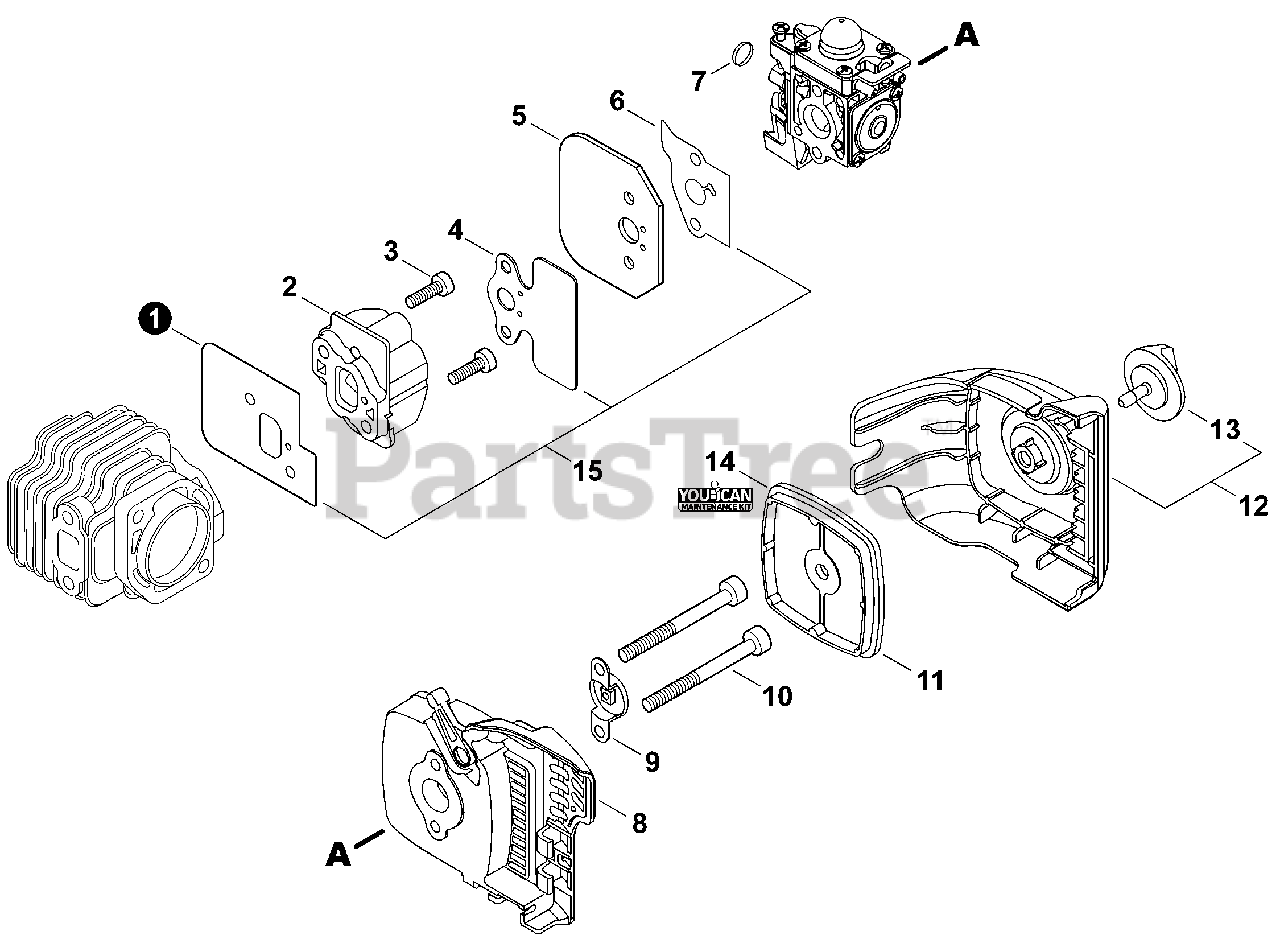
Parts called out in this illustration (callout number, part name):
1	GASKET, INTAKE
2	INSULATOR, INTAKE
3	BOLT, TORX 5×25
4	GASKET, INTAKE
5	PLATE, INSULATOR
6	GASKET, INTAKE
8	CASE, AIR FILTER
9	PLATE, PREVENT
10	BOLT, TORX 5×65
11	FILTER, AIR - DOUBLE LAYER
12	COVER SET, AIR FILTER
13	THUMBSCREW
14	PLUG & FILTER KIT - YOU CAN
15	GASKET KIT
